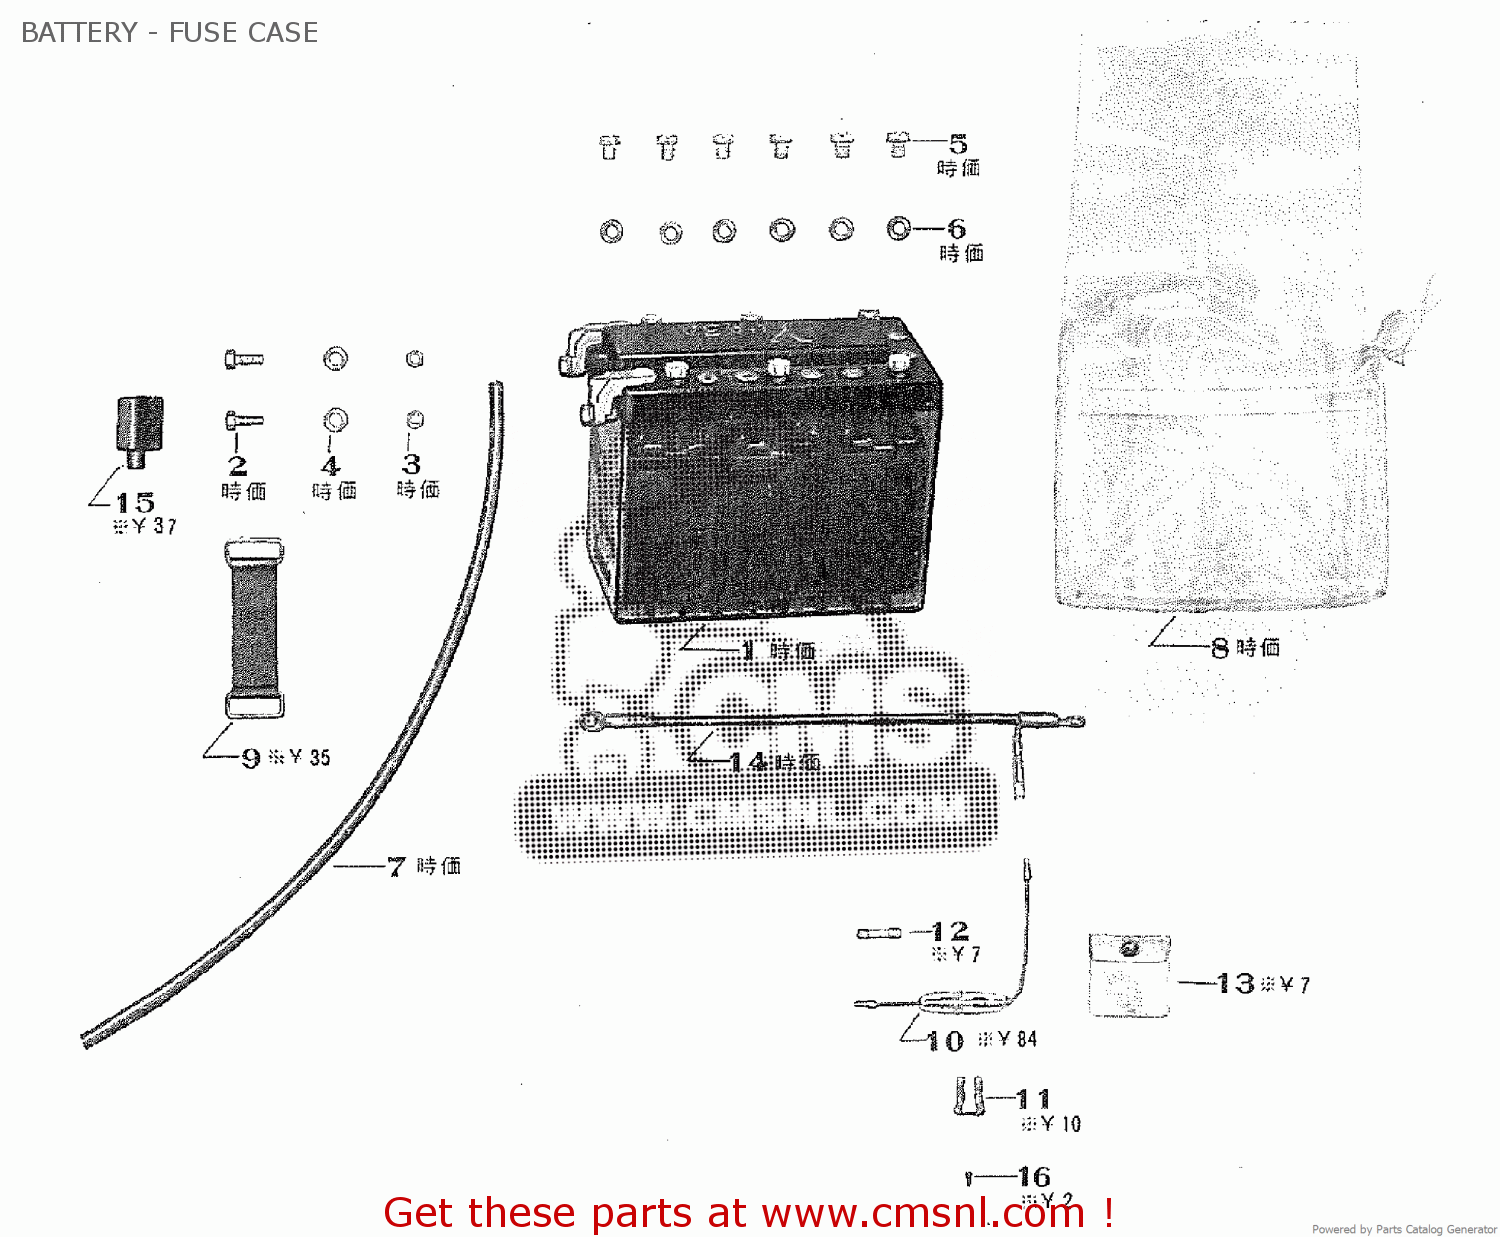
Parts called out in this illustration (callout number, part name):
1	BATTERY ASSY.
2	TERMINAL BOLT
3	TERMINAL NUT
4	TERMINAL WASHER
5	BATTERY PLUG
6	BATTERY PLUG PACKING
7	EXHAUST TUBE
8	BATTERY BAG
9	BATTERY SET BAND
10	FUSE CASE ASSY.
11	FUSE CASE HOLDER
12	FUSE
13	FUSE BAG
14	BATTERY LEAD CORD
15	BATTERY TERMINAL BUSH
16	6X8 CROSS SCREW
